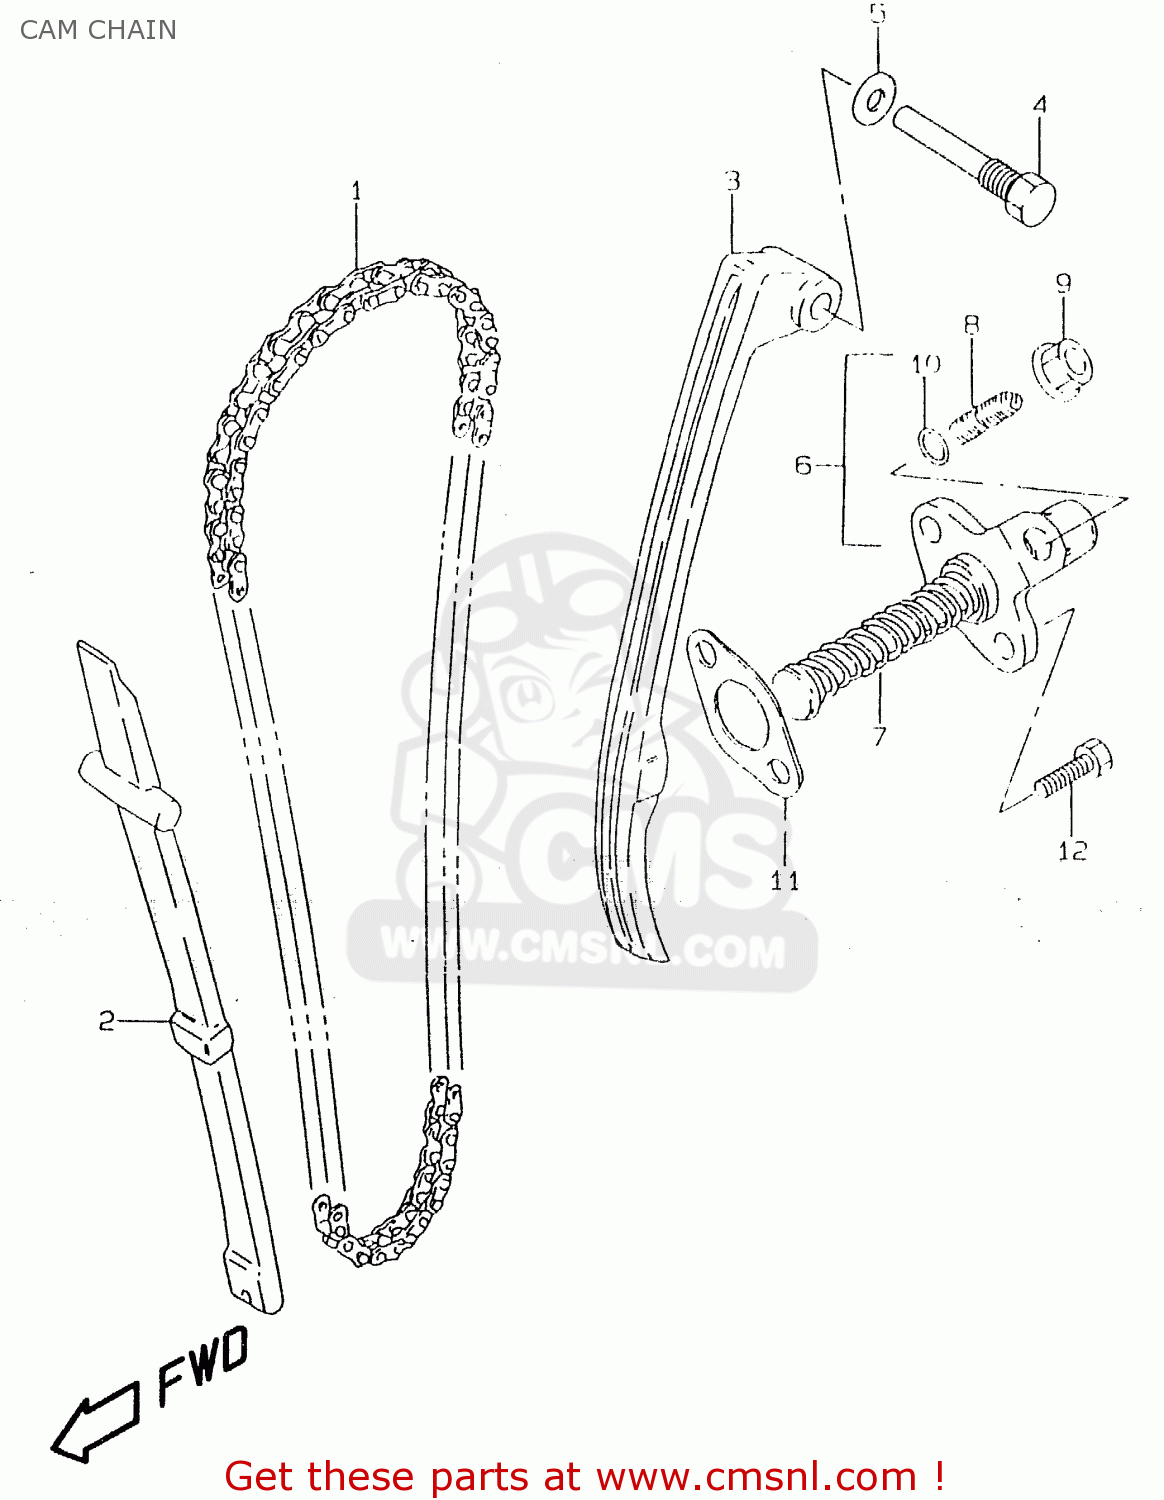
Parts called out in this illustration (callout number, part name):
1	CHAIN,CAMSHAFT DRIVE
2	GUIDE,CAM CHAIN
3	TENSIONER,CAM CHAIN
4	BOLT,CAM CHAIN TENSIONER
5	GASKET 8.2X14X1 (NAS)
6	ADJUSTER ASSY,TENSIONER
7	SPRING
8	SCREW
9	NUT
10	O RING(D:1.9,ID:5.7)
11	GASKET,TENSIONER ADJUSTER (NAS)
12	BOLT
